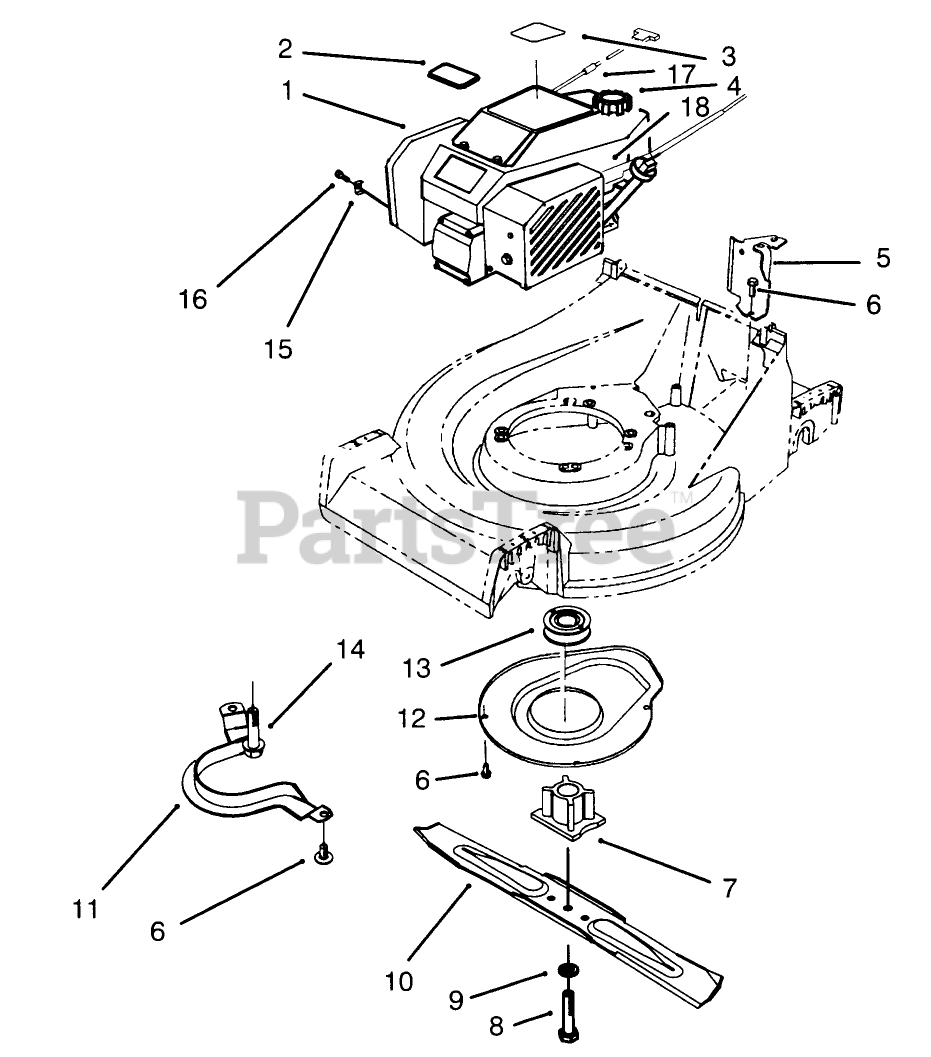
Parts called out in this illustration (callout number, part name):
4	CAP-GAS
6	SCREW-HWHTF
7	BLADE RETAINER
8	SCREW-BLADE
9	WASHER-LOCK
13	PULLEY-DRIVE, ZONE START
14	SCREW-HWH
15	CLAMP-CASING
16	CLAMP SCREW F/W ENGINE
17	STOP-ROPE
18	COVER - BRAKE F/W
